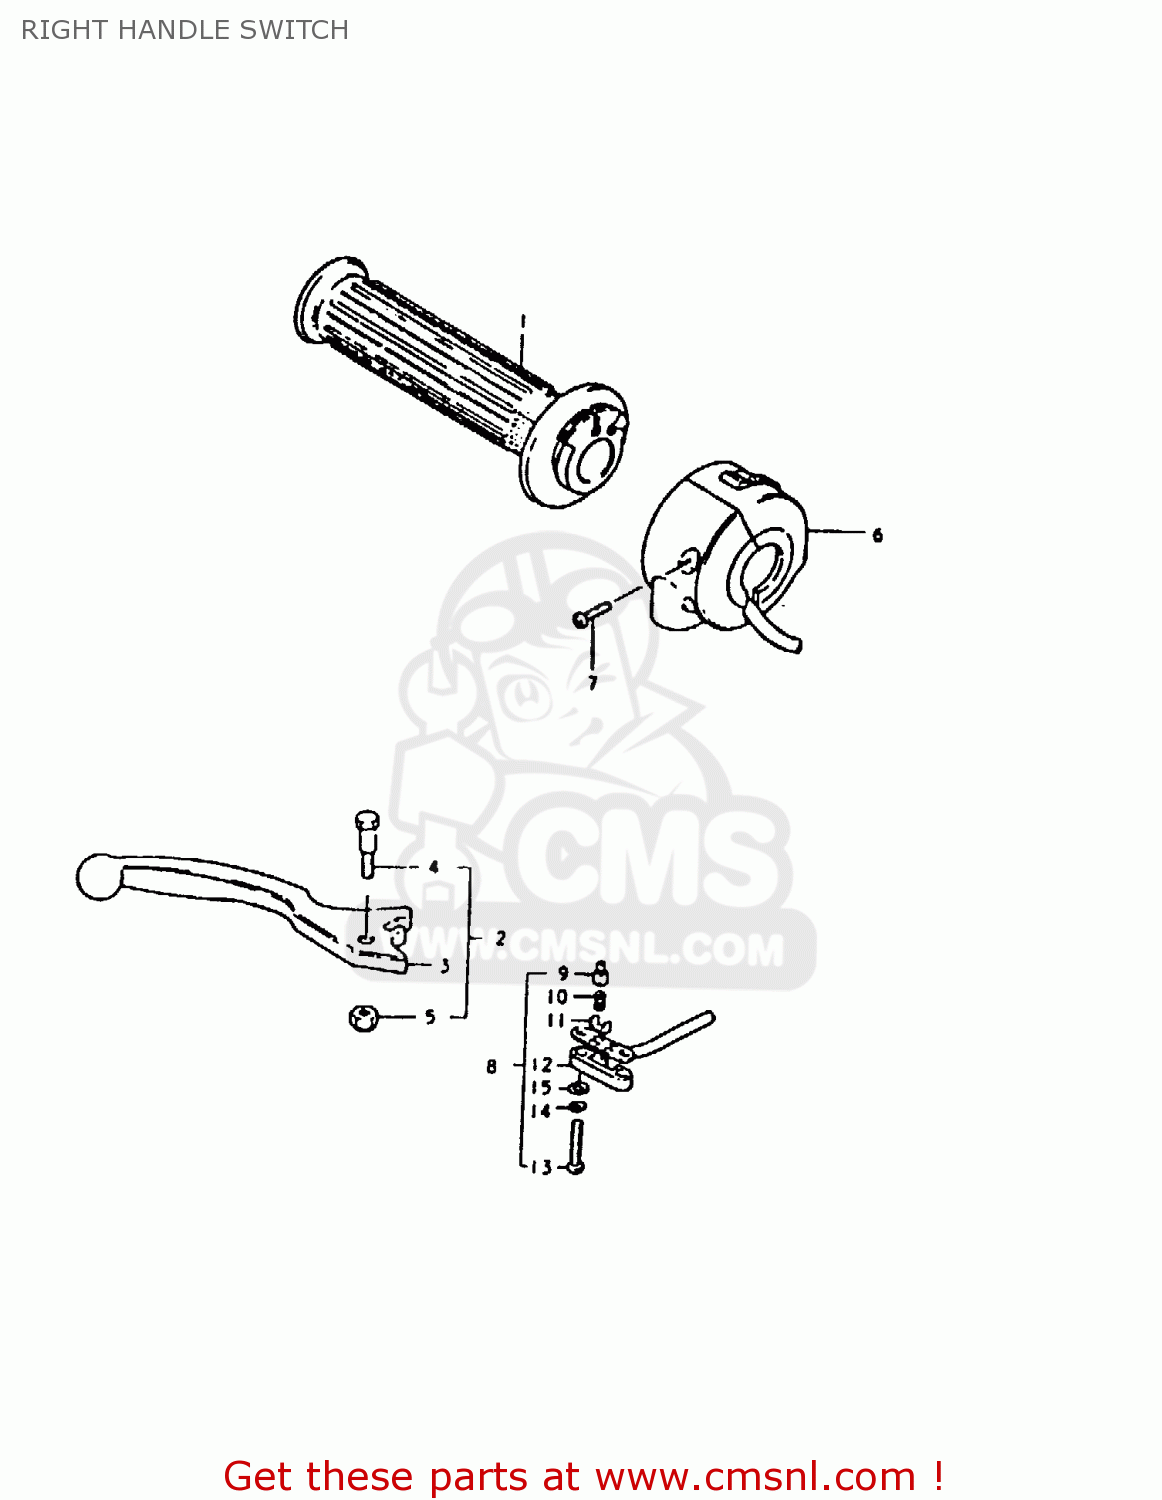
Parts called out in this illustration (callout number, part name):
1	GRIP,THROTTLE
2	LEVER ASSEMBLY,BRAKE
3	LEVER,BRAKE
4	BOLT
5	NUT 6MM
6	SWITCH ASSY, HANDLE RH
7	SCREW
8	SWITCH ASSEMBLY
9	HOLDER
10	SPRING
11	PLATE
12	COVER,FR BK TERMINAL BASE
13	SCREW
14	LOCK WASHER
15	WASHER
